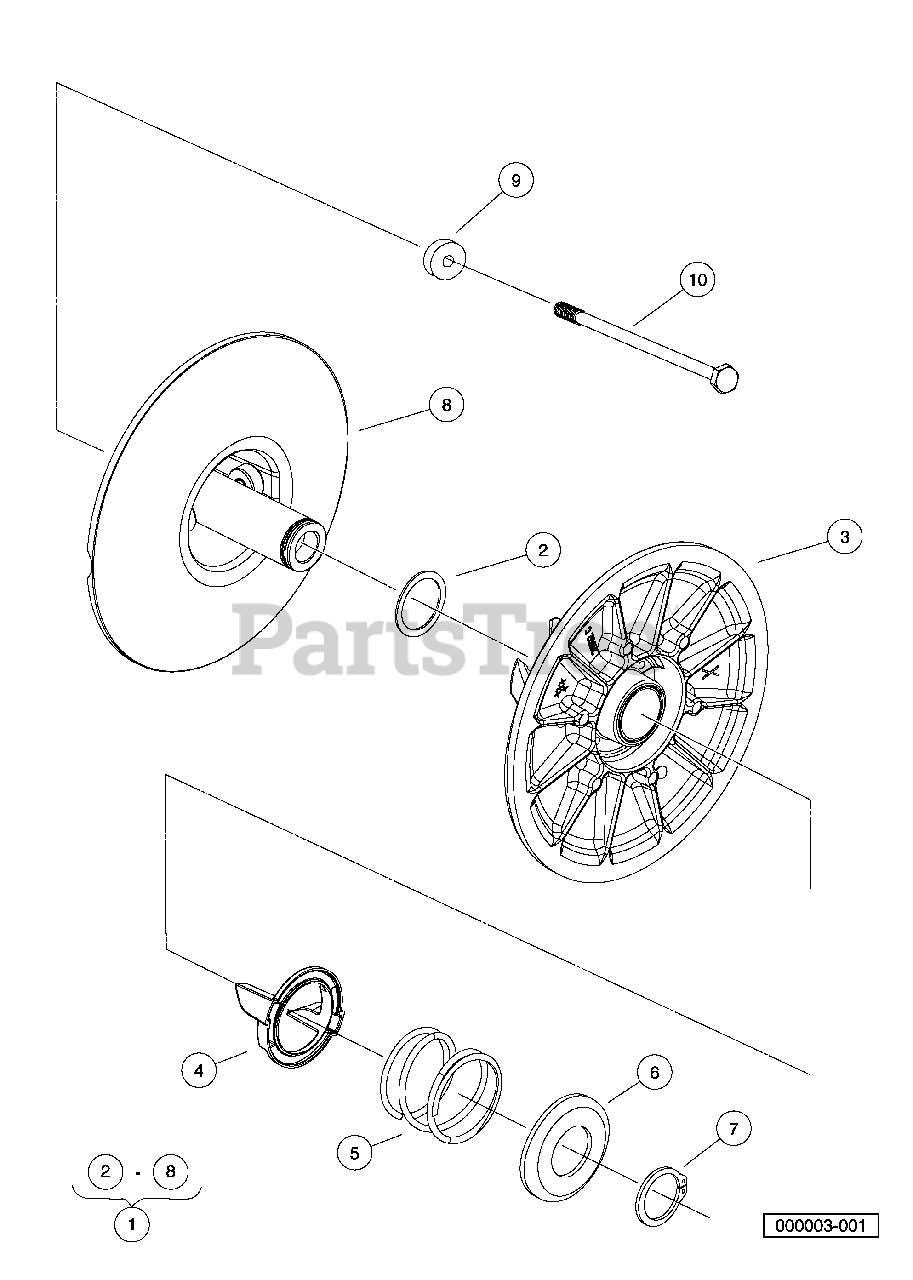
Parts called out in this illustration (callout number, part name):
1	CVT, Secondary
2	Washer, Thrust, 1.53 X 1.92
3	Sheave, Driven Clutch
4	Retainer, Spring, Inner
5	Spring, Compression, Secondary
6	Retainer, Spring, Outer
7	Ring, Retaining, External
8	Driven Clutch Base Sheave
9	Washer, Stepped
10	Bolt, M10 X 1.5 X 100 Loctite
